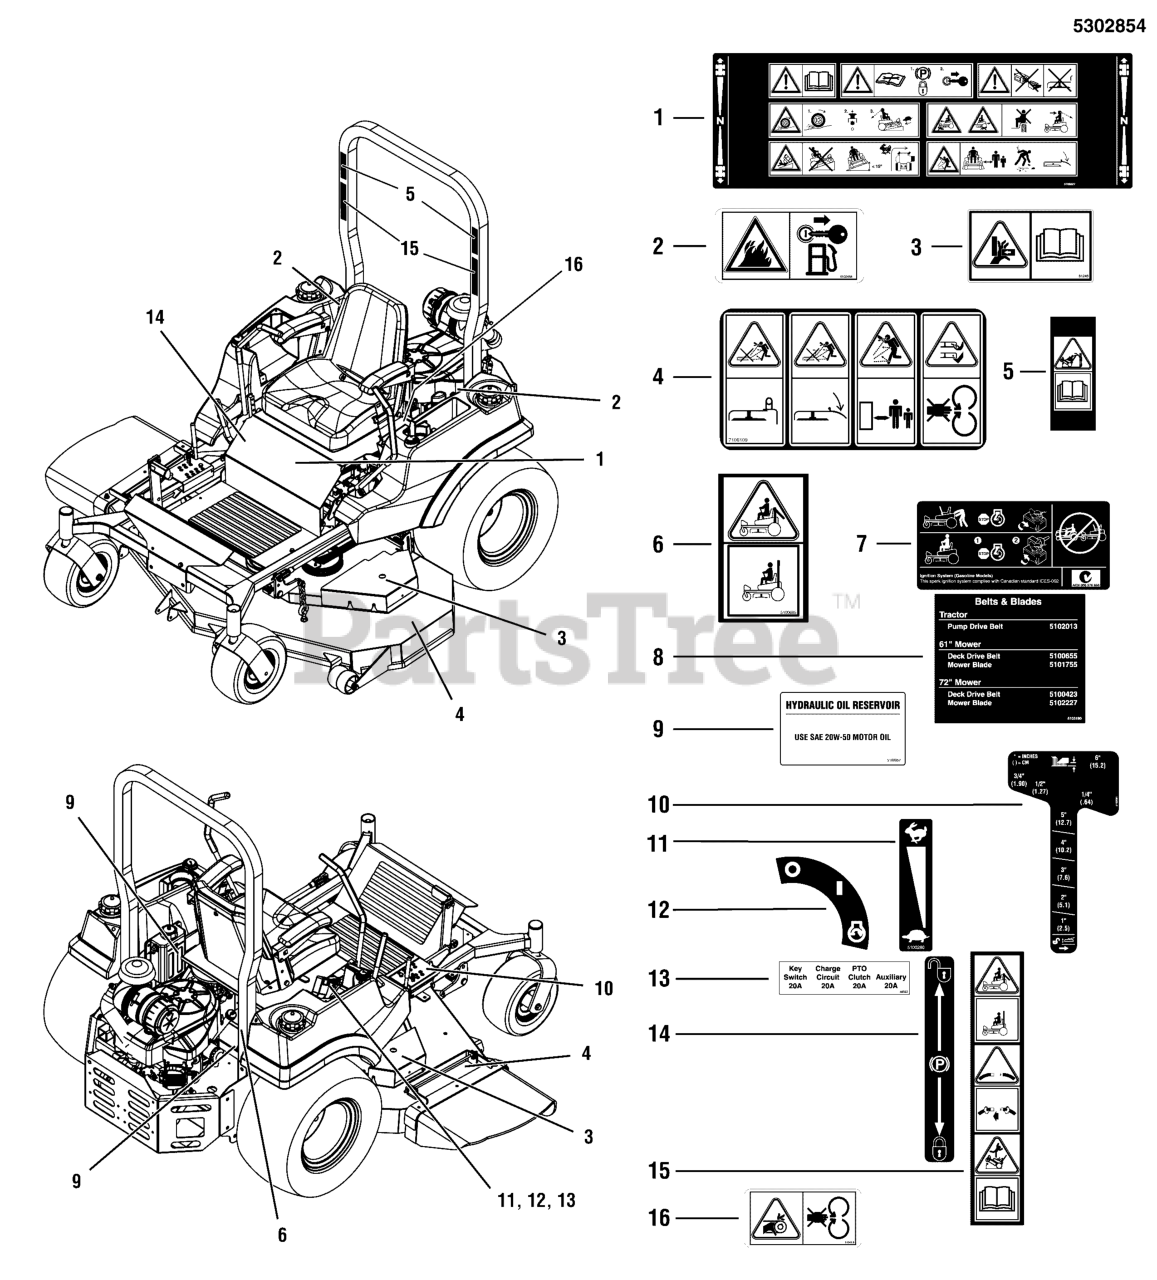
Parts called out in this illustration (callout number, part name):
1	DECAL, MAIN SAFETY, ANSI CE
2	DECAL, FIRE ANSI EXPORT
3	DECAL, PINCH POINT, CE
4	DECAL, DISCHARGE SAFETY, EXPORT
5	DECAL, SAFETY, CE ROPS, OBS
6	DECAL, WARNING, ROLL BAR, CE
7	DECAL, TRANSAXLE RELEASE, S200XT
8	DECAL, BELT & BLADE, S200XT-72
9	DECAL, HYDRAULIC OIL, SAE 20W50
10	DECAL, DECK HEIGHT, 1-1/2 TO 6, S200XT
11	DECAL, THROTTLE CONTROL
12	DECAL, IGNITION SWITCH
13	DECAL, FUSE LOCATION, 20-20-20-20
13	DECAL, FUSE LOCATION, 20-15-15-20
14	DECAL, PARKING BRAKE SYMBOLS
15	DECAL, SAFETY, CE ROPS
16	DECAL, CE DANGER
